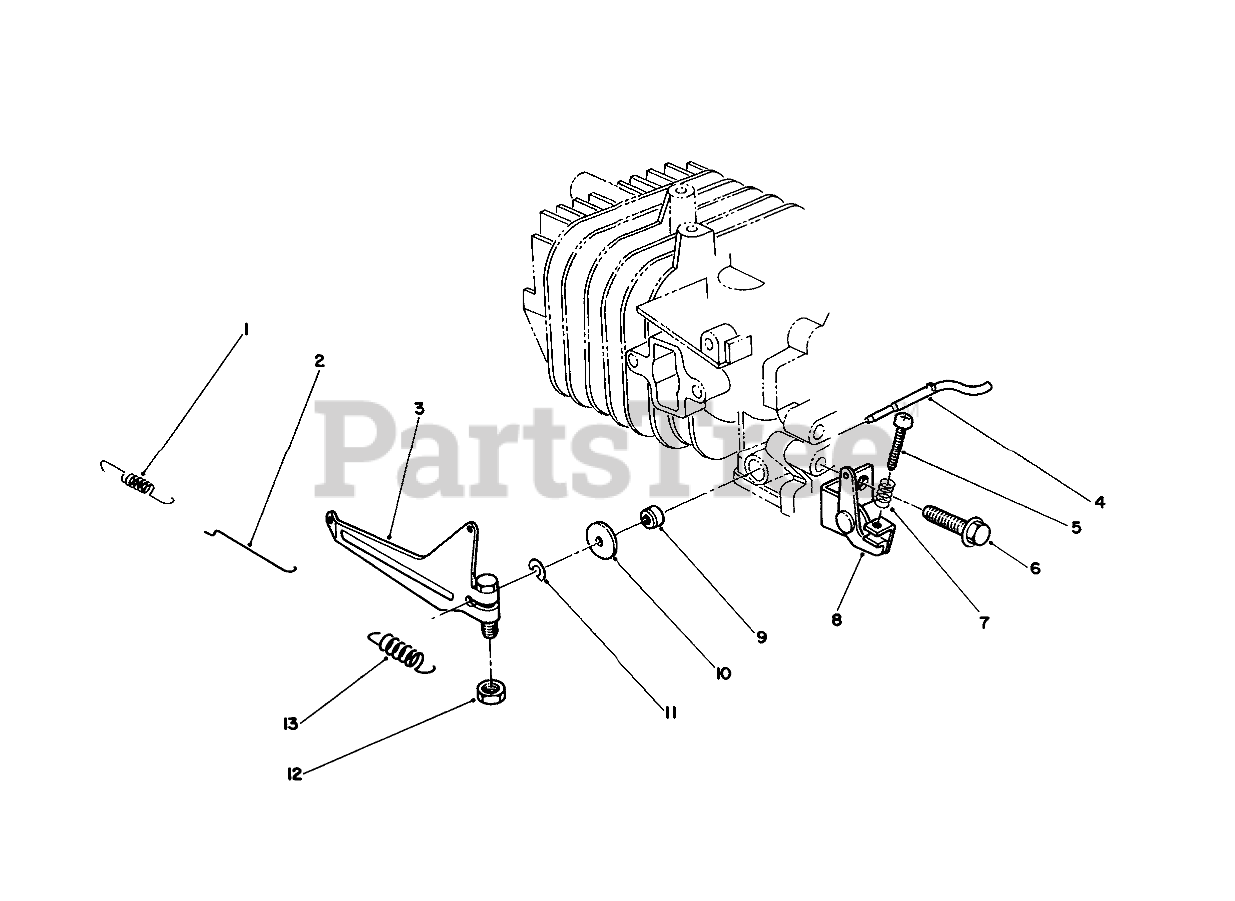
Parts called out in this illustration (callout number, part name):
1	CARB SPRING
2	CARB ROD
3	GOV ARM
4	SHAFT
5	SCREW
7	SPRING
8	GOV SPR BRKT
9	SEAL-OIL
10	WASHER
11	E-RING
13	GOV SPRING
